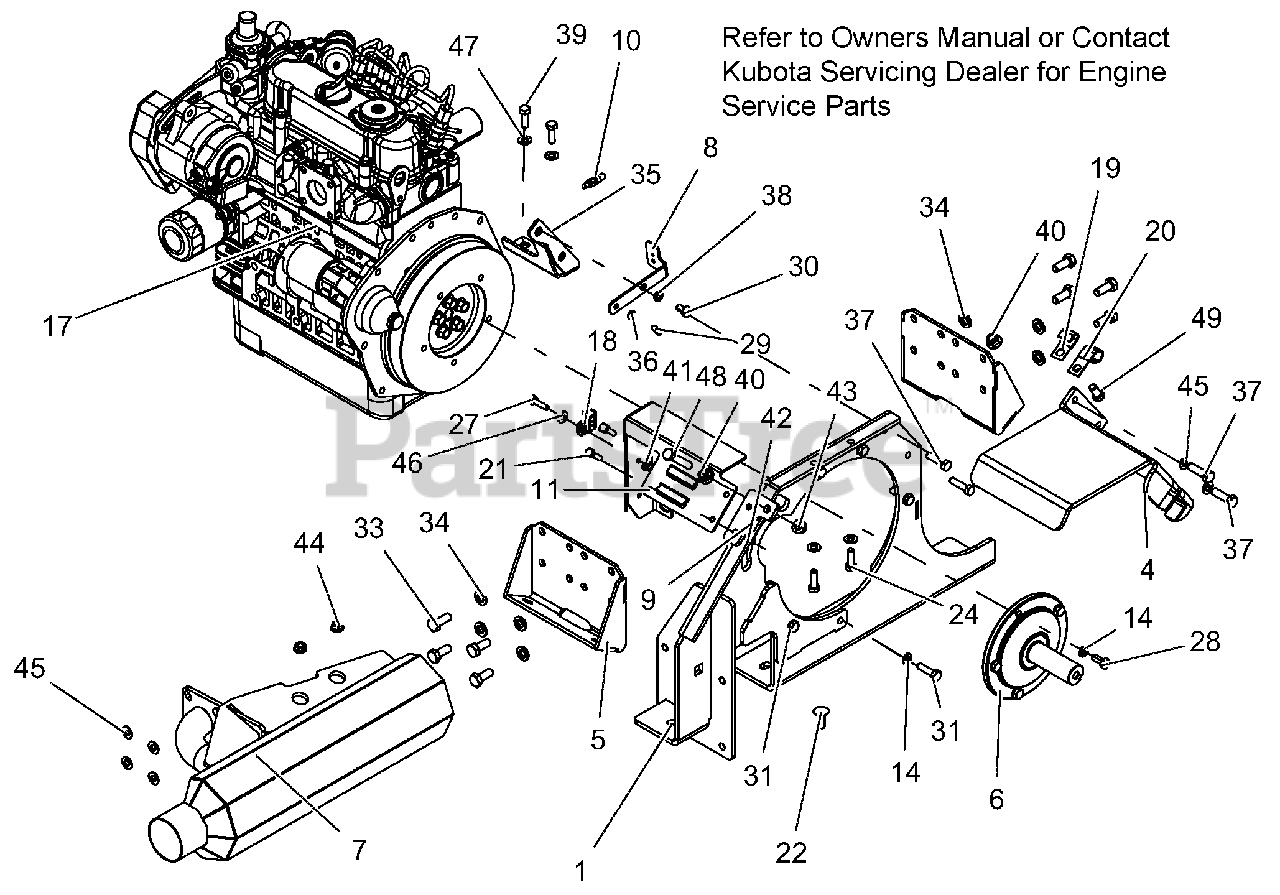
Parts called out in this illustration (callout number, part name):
1	WLDMT, ENGINE /GEARBOX MNT-BLACK
4	WLDMT, DIESEL CLUTCH STOP-BLACK
5	WLDMT, FRONT ENGINE MOUNT
6	SHAFT, STUB KUBOTA DIESEL MACHINED
7	MFLR, DIESEL PT-400
8	BRKT, THROTTLE CABLE
9	SPRG, ANCHOR
10	SENDER, WATER TEMPERATURE
11	BRKT, HEAT DEFLECTOR LOUVERED
14	WSHR, LOCK M8 YWZC
17	KUBOTA_D902_E3B_WITHOUT_RADIATOR
18	CLAMP, CUSHIONED STEEL
19	, J-CLAMP
21	BLT-HEX .25-20X1.00 GR5 YWZC
22	@BLT-RDHDSQNK .38-16X1.00 G5 YWZC
24	BLT-HEX .31-18X1.00 GR5 YWZC
25	BLT-HEX .38-16X2.00 GR8 YWZC
27	BLT-HEX .25-20X1.00 GR5 YWZC
28	@BLT-HEX M8-1.25X20 YWZC
29	BLT-HEX M6 X 1.0X10 YWZC
30	@BLT-HEX M8 X 1.25X14 YWZC
31	@BLT-HEX M8 X 1.25X30 GR5 YWZC
33	BOLT, HEX M10-1.25 X 25 YWZC
34	@WSHR-LK .44X.109 REG YWZC
35	WLDMT, DIESEL FUEL FILTER MOUNT
36	@WSHR-LK .25X.062 REG YWZC
37	BLT-HEX .31-18X1.25 GR5 YWZC
38	@WSHR-LK .31X.078 REG YWZC
39	BLT-HEX .31-18X1.00 GR5 YWZC
40	NUT-LK-NYL-FLG .38-16 YWZC
41	NUT-LK-NYL-FLG .25-20 YWZC
42	NUT-LK-NYL-FLG .25-20 YWZC
43	@NUT-SPNLK-FLG .375-16 YWZC
44	@NUT-SPNLK-FLG .312-18 YWZC
45	@WSHR-FL-STL.344X.688X.065YWZC
46	@WSHR-FL-STL.281X.62X.065 YWZC
47	@WSHR-FL-STL.344X.688X.065YWZC
48	BLT-HEX .38-16X2.00 GR8 YWZC
49	BLT-HEX .38-16X.75 GR5 YWZC
